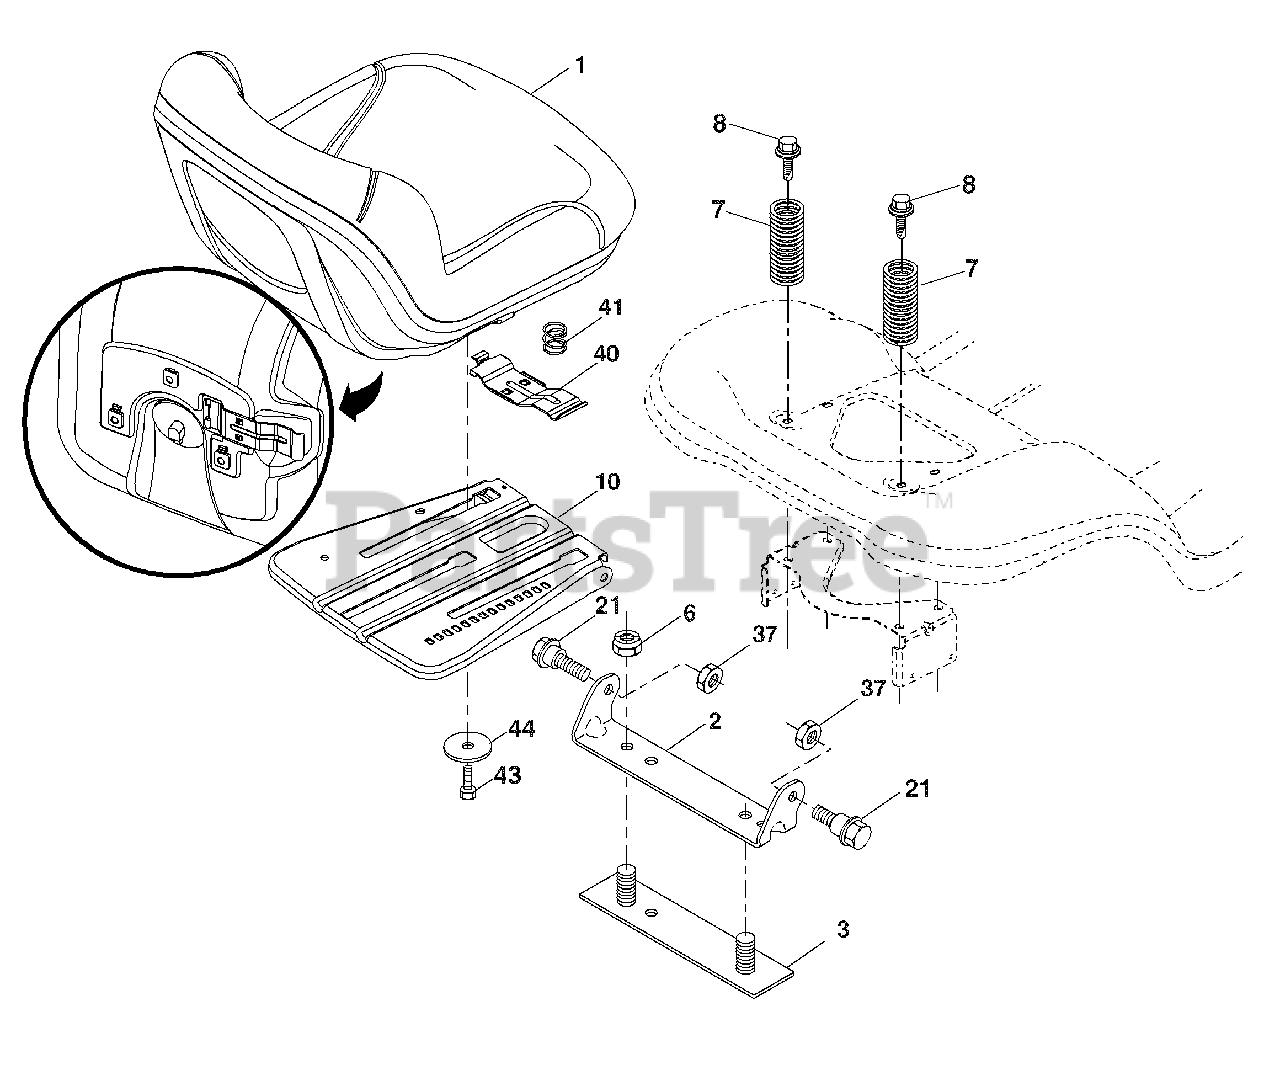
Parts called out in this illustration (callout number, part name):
1	Seat
2	Bracket Pivot Fender
3	Strap, Asm Fender
6	Nut, Lock w/Ins. 3/8-16 unc
7	Spring, Seat Cprsn
8	Bolt 5/16-18 unc x 3/4 w/Sems
10	Pan, Seat
21	Bolt, Shoulder 5/16-18
37	Nut, Lock 5/16-18 unc
40	Handle Slide Seat
41	Spring Latch Seat
43	Bolt 3/8-16 x 3/4
44	Washer 13/32 x 2-3/8 x 12 Ga.
